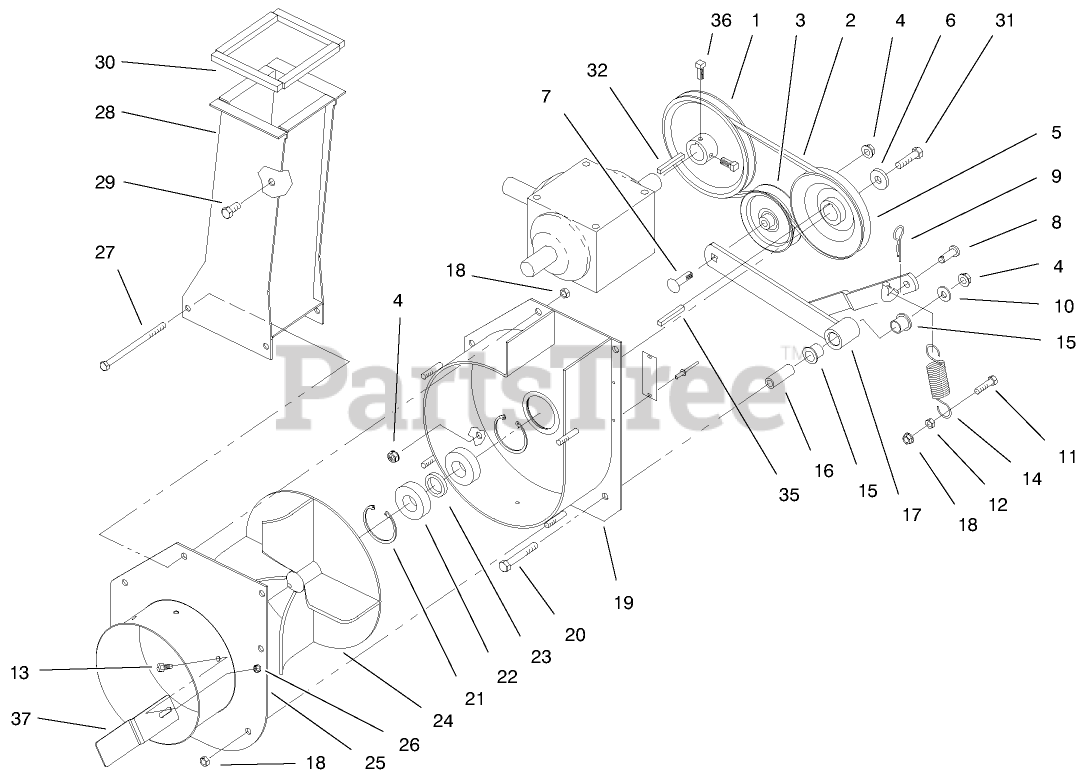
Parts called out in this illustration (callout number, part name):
1	PULLEY-GEARBOX
2	V-BELT
3	PULLEY-IDLER
4	NUT-HF
5	PULLEY - IMPELLER B
6	WASHER-THRUST, PLAIN
7	SCREW-CARR
8	PIN-CLEVIS
9	PIN-HAIR
10	WASHER-FLAT
11	SCREW-HH
12	NUT-HEX
13	SCREW-PPH
14	SPRING-EXTENSION
15	BUSHING-FLANGE
16	SPACER
17	Idler Arm
18	NUT-HF
19	Housing
20	SCREW-HH
21	RING-SNAP
22	BEARING-BALL
23	SPACER-BEARING
24	Impeller
25	Cover
26	NUT-HHF
27	SCREW-HH
28	Impeller Chute
29	SCREW-HH
30	STRIP - FOAM
31	SCREW-HH
32	KEY-SQUARE
35	KEY-SQUARE
36	SCREW-SET, SQH
37	Guide-Plenum
